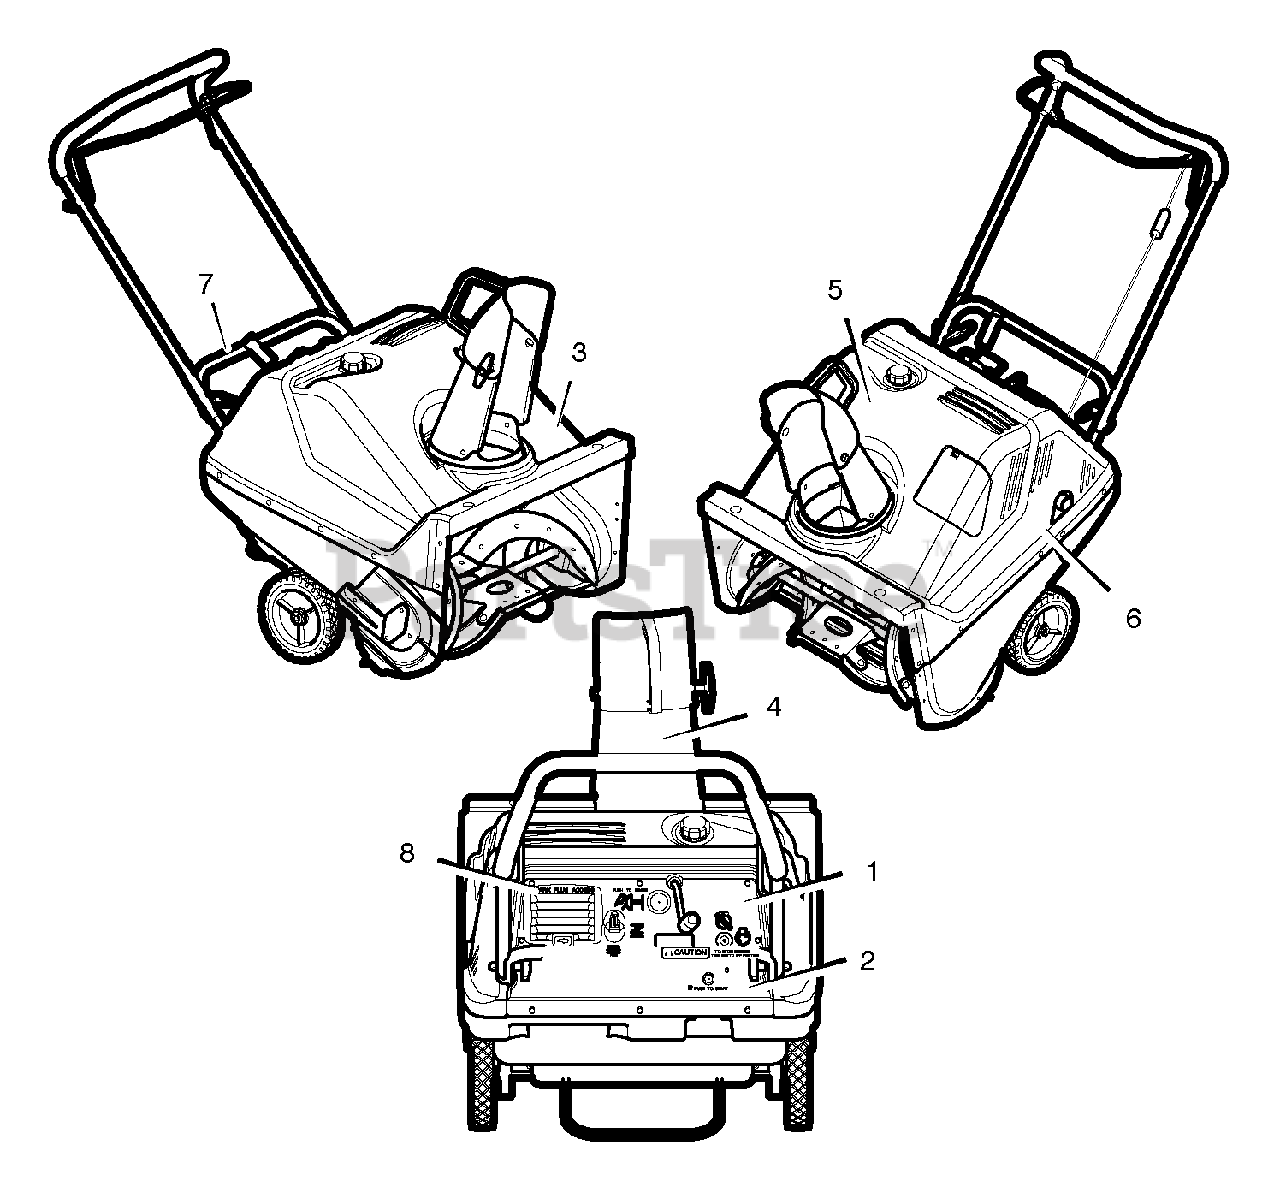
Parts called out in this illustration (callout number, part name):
1	Decal, Panel 22" ES SEARS
2	Decal, Electric Start
3	Decal, Auger Danger
4	Decal, Danger Chute Hand
5	Decal, 5HP/22" CRAFTSMAN
6	Decal, Danger Muffler
7	Decal, Auger Control
8	Decal, Spark Plug Access 22"
